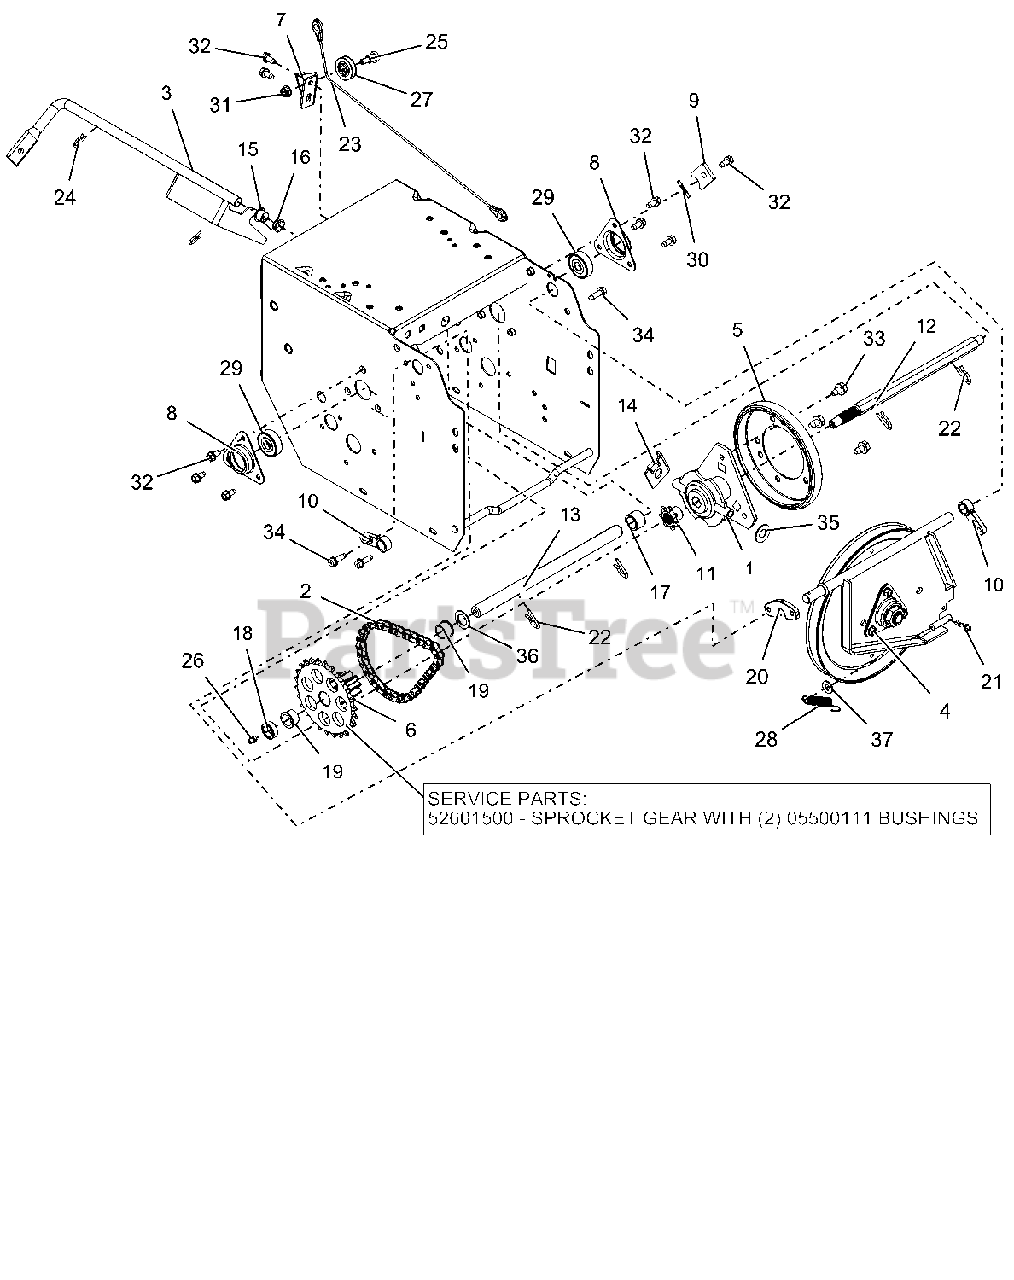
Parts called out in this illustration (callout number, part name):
1	CARRIER, DRIVE DISK
2	CHAIN - #41, 32 PITCHES
3	WELDMENT, SHIFT FORK
4	PLATE, SWING - ASSEMBLY
5	FRICTION, DISC
6	PINION & SPROCKET
7	BRACKET, CABLE PULLEY
8	FLANGE, BEARING
9	TAB, ANTI ROTATION
10	SUPPORT BUSHING, SWING GATE
11	SPROCKET, PINION 7T W/SPLINE
12	SHAFT, HEX W/SPLINE TRACK
13	SHAFT, PINION TRACK
14	BRACKET, FORMED - SHIFT FORK
15	BUSHING, POLYLINER-.50 SPLIT
16	BUSHING, POLYLINER-.50 SNAPIN
17	SPACER, .635X.880X.611
18	BSHG-SLV, .635X.880X.305
19	BSHG-FLG .625X.750X.500X.875
20	SPACER, SWING GATE
21	PIN-HAIR INT .08X.18X1.18 YWZC
22	PIN, SPRING CLIP
23	CABLE, LOWER TRACTION (CMPCT)
24	CLIP, SPRING
25	BOLT, SHLDR-.375X.375X.25-20
26	ZERK,FITTING .25X.125 DRIVE IN
27	PULLEY, CABLE
28	SPRING, EXT. .043X.438X1.64
29	BRG-BALL .437X1.375X.437
30	@PIN-GRV .125X1.00 TP E ALLOY
31	@NUT-LK-CTR-FLG .25-20 YWZC
32	SCR-TAP .25-20X.50 HWH TR YWZ
33	@SCR-TAP .31-18X.50 HWH TR YWZ
34	SCR-TAP-PM .25-20X.75 TR YWZ
35	WSHR-FL-STL .505X1.00X.062YWZC
36	WSHR-FL-STL .630X1.005X.062 YZ
37	@WSHR-FL-STL.344X.688X.065YWZC
38	PINION & SPROCKET W/BUSHINGS
39	BSHG-FLG .625X.750X.500X.875
